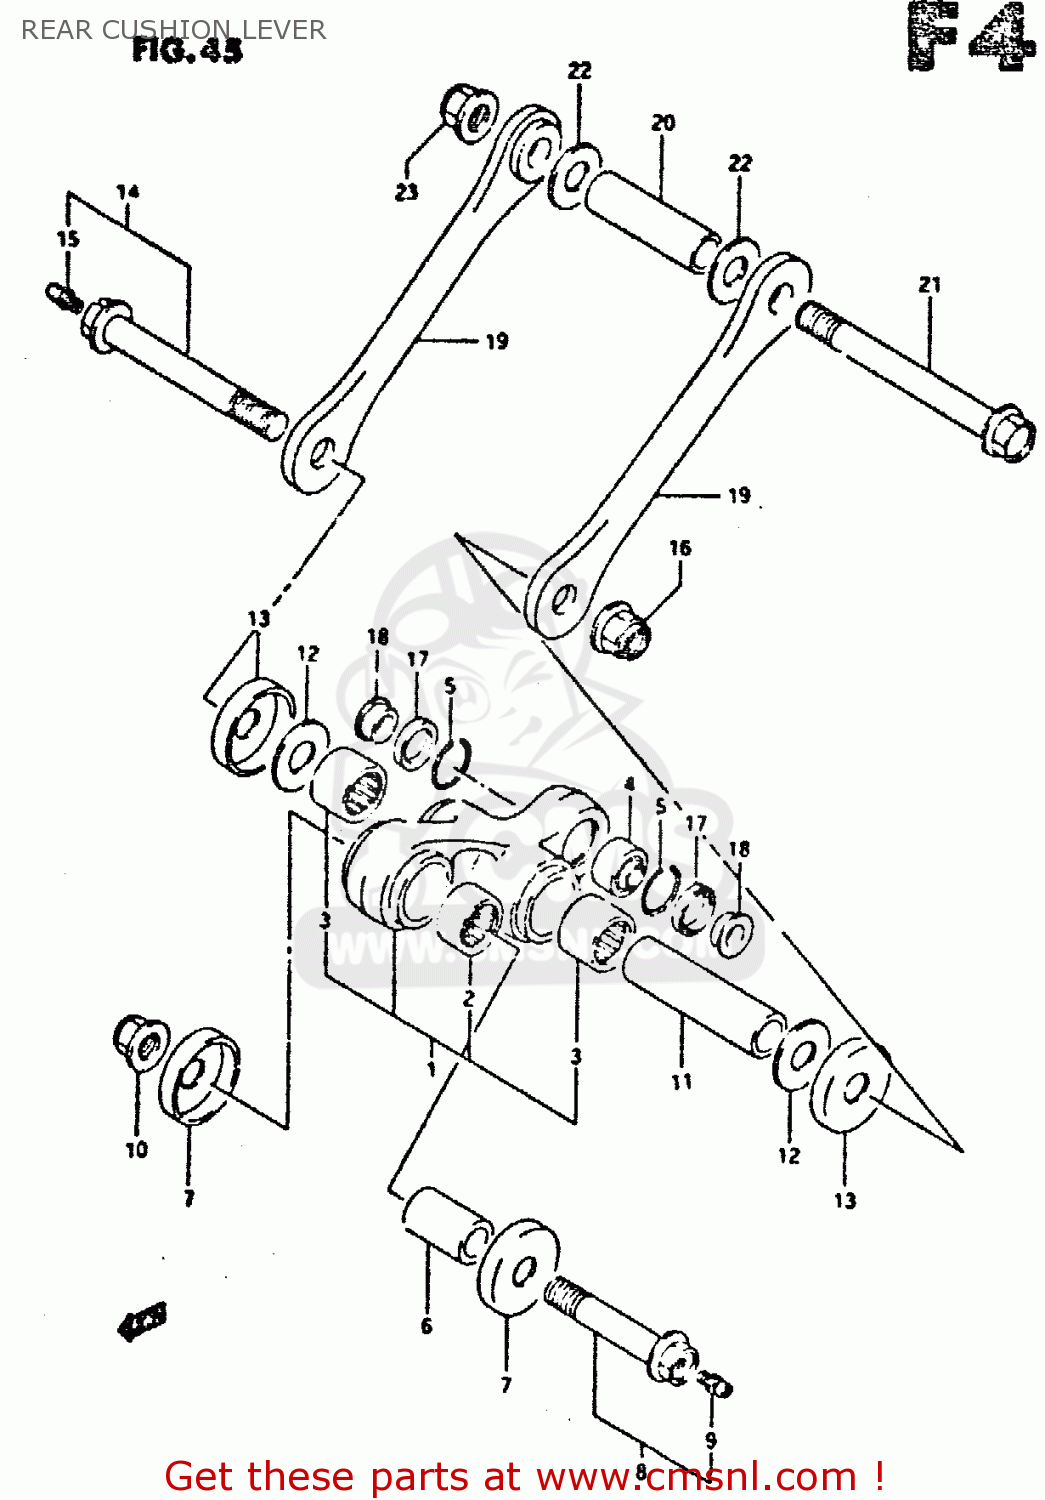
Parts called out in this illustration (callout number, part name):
1	LEVER SET,RR CUSHION
2	BEARING(20X27X32)
3	BEARING(20X27X23.5)
4	BEARING,RR CUSHION LEVER
5	RING,STOPPER
6	SPACER,RR CUSHION LEVER FR
7	SEAL,REAR CUSHION LEVER
8	BOLT,RR CUSHION LEVER FR
9	GREASE NIPPLE
10	NUT 12MM
11	SPACER,RR CUSHION LEVER CTR
12	WASHER
13	SEAL,RR CUSHION LEVER
14	BOLT,RR CUSHION LEVER CTR
15	GREASE NIPPLE
16	NUT
17	SEAL,OIL(17X24X3)
18	COLLAR
19	ROD,RR CUSHION
20	SPACER,RR CUSHION ROD
21	BOLT,RR CUSHION ROD
22	WASHER
23	NUT
